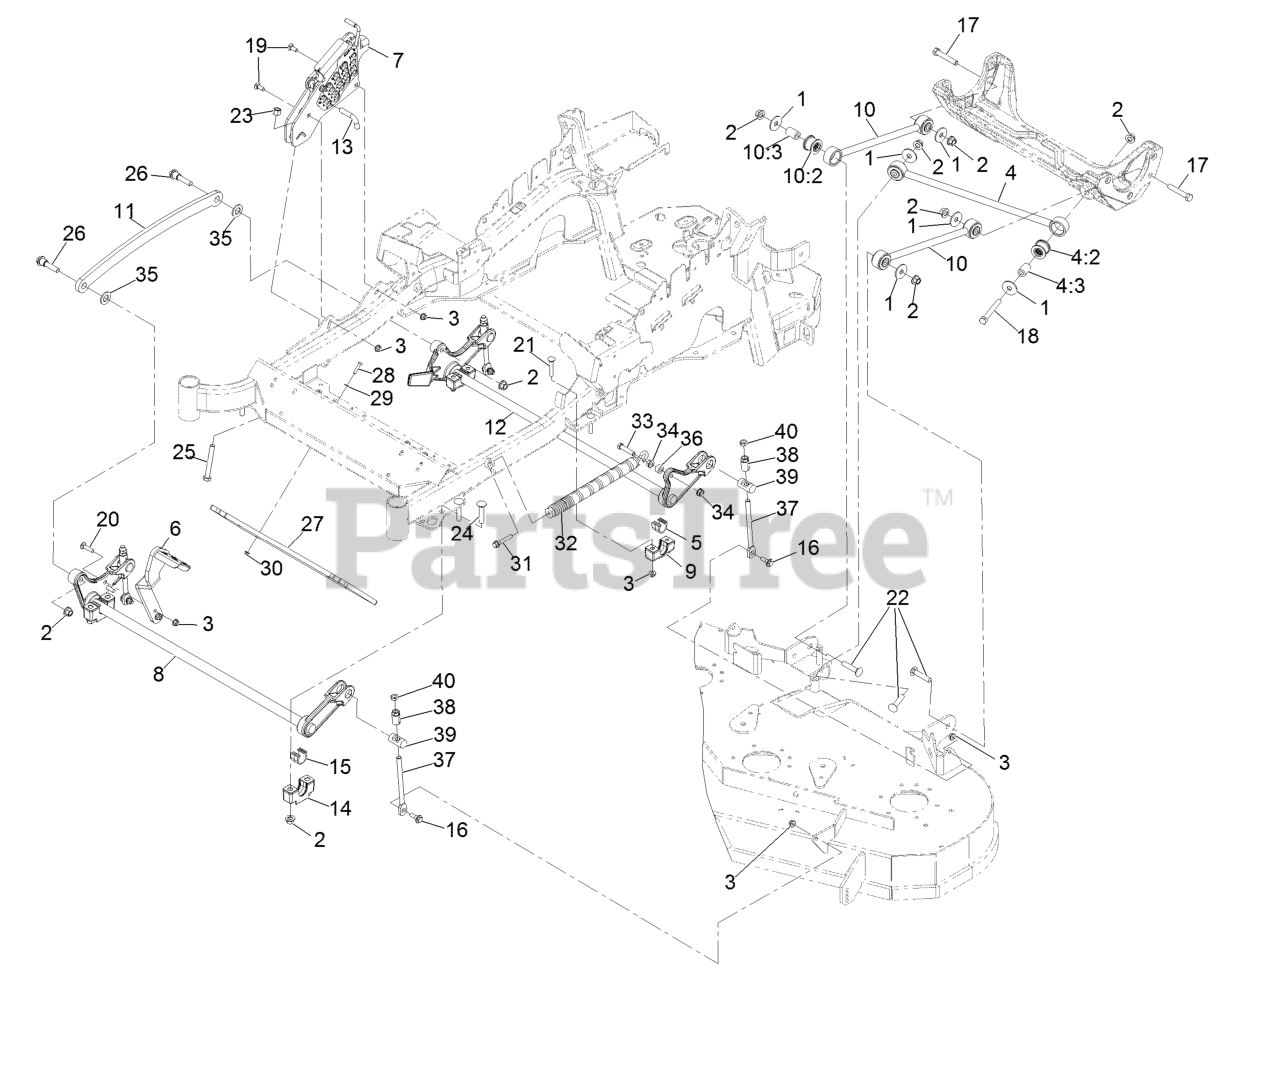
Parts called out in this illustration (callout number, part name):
2	Nut-Lock 1/2-13
3	Nut-Nyloc 3/8-16 Flg
4	Panhard Rod ASM
4:2	Bushing-Suspension, Rubber
5	Bearing-Cross Shaft, Rear
6	Lever-Foot
7	HOC ASM
8	Decklift-Front
9	Support-Cross Shaft, Bearing Rear
10	Deck Strut ASM
10:2	Bushing-Suspension, Rubber
11	Link-Lift, Deck
12	Lift-Deck, Rear
13	Pin-HOC
14	Support-Cross Shaft, Bearing
15	Bearing-Cross Shaft, Front
16	Screw-Hex Flange 3/8-16 X .80
17	Screw-HH 1/2-13 X 3
18	Screw-HH 1/2-13 X 4
19	Bolt-Carriage 3/8-16 X 1
20	Bolt-Carriage 3/8-16 X 1 1/2
21	Bolt-Carriage 3/8-16 X 2 1/4
22	Bolt-Carriage 1/2-13 X 2 1/2
23	Nut-Nyloc 1/2-13
24	Bolt-Carriage 1/2-13 X 2 1/2 Spl Neck
25	Bolt-HH 1/2-13 X 4 Tap
26	Screw-Hex Flange 1/2-13 X 1.90
27	Weight-Toe Board
28	Screw-HH 1/4-20 X 1 1/4
29	Washer-1/4 SAE
30	Nut-Nyloc 1/4-20 Flg
31	Screw-Shcs 3/8-16 X 2.212
32	Spring-Extension
33	Screw-HH 7/16-14 X 2
34	Nut-Whizlock 7/16-14
35	Washer-3/4 SAE
37	Link-Adjuster, Deck Lift
38	Adjuster-Lift, Deck
39	Trunnion
40	Nut-Jam 1/2-13
